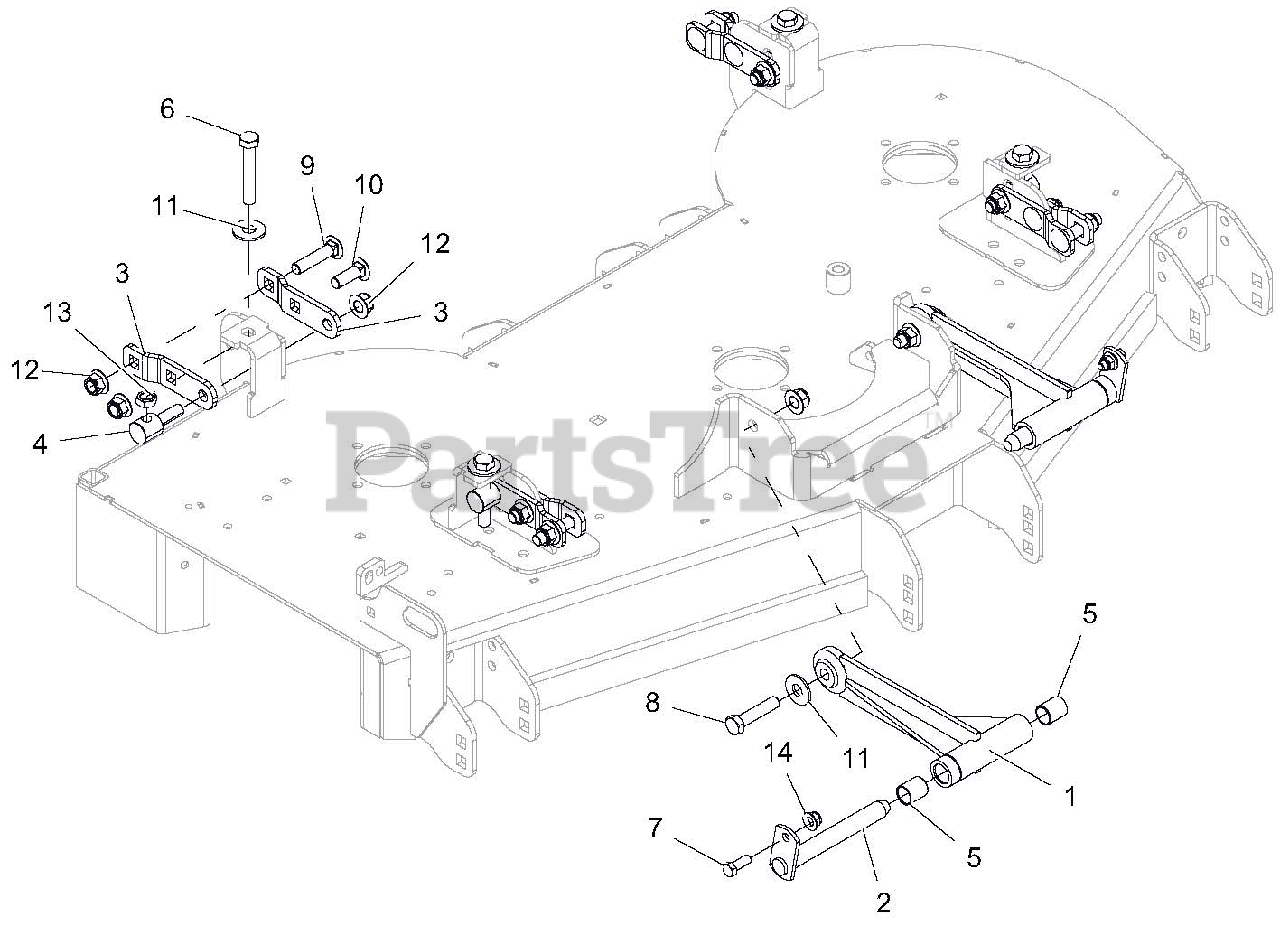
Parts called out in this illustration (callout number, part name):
1	WLDMT, DRAG LINK
2	WLDMT, MOWER MTG. PIN
3	BRKT, DECK LEVELING
4	TRUNNION, .50-13
5	BRG, .750 X .875 X 1.000
6	BLT-HEX .50-13X3.00 GR5 FTH YWZC
7	BLT-HEX .38-16X1.00 GR5 YWZC
8	BLT-HEX .50-13X2.25 GR5 YWZC
9	BLT-RDHDSQNK .50-13X2.25 G5 Y
10	BLT-RDHDSQNK .50-13X1.50 G5 YWZC
11	WSHR-FL-STL.563X1.38X.109YWZC
12	NUT-LK-NYL-FLG .50-13 YWZC
13	NUT, JAM .500-13 YWZC
14	NUT-LK-NYL-FLG .38-16 YWZC
